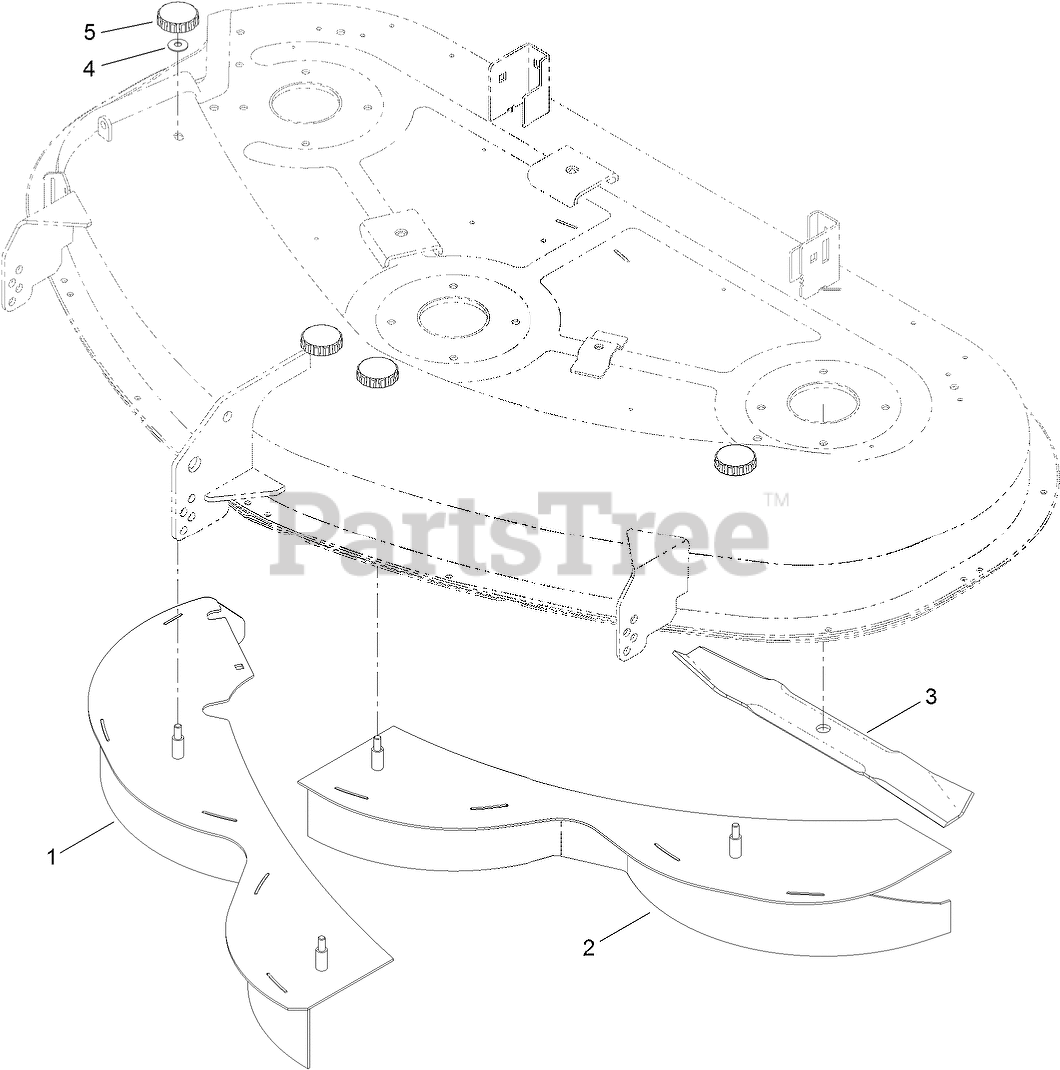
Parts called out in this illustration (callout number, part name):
1	RH BAFFLE ASM
2	LH BAFFLE ASM
3	BLADE-MULCH, 17.50 INCH
4	WASHER-BELLEVILLE
